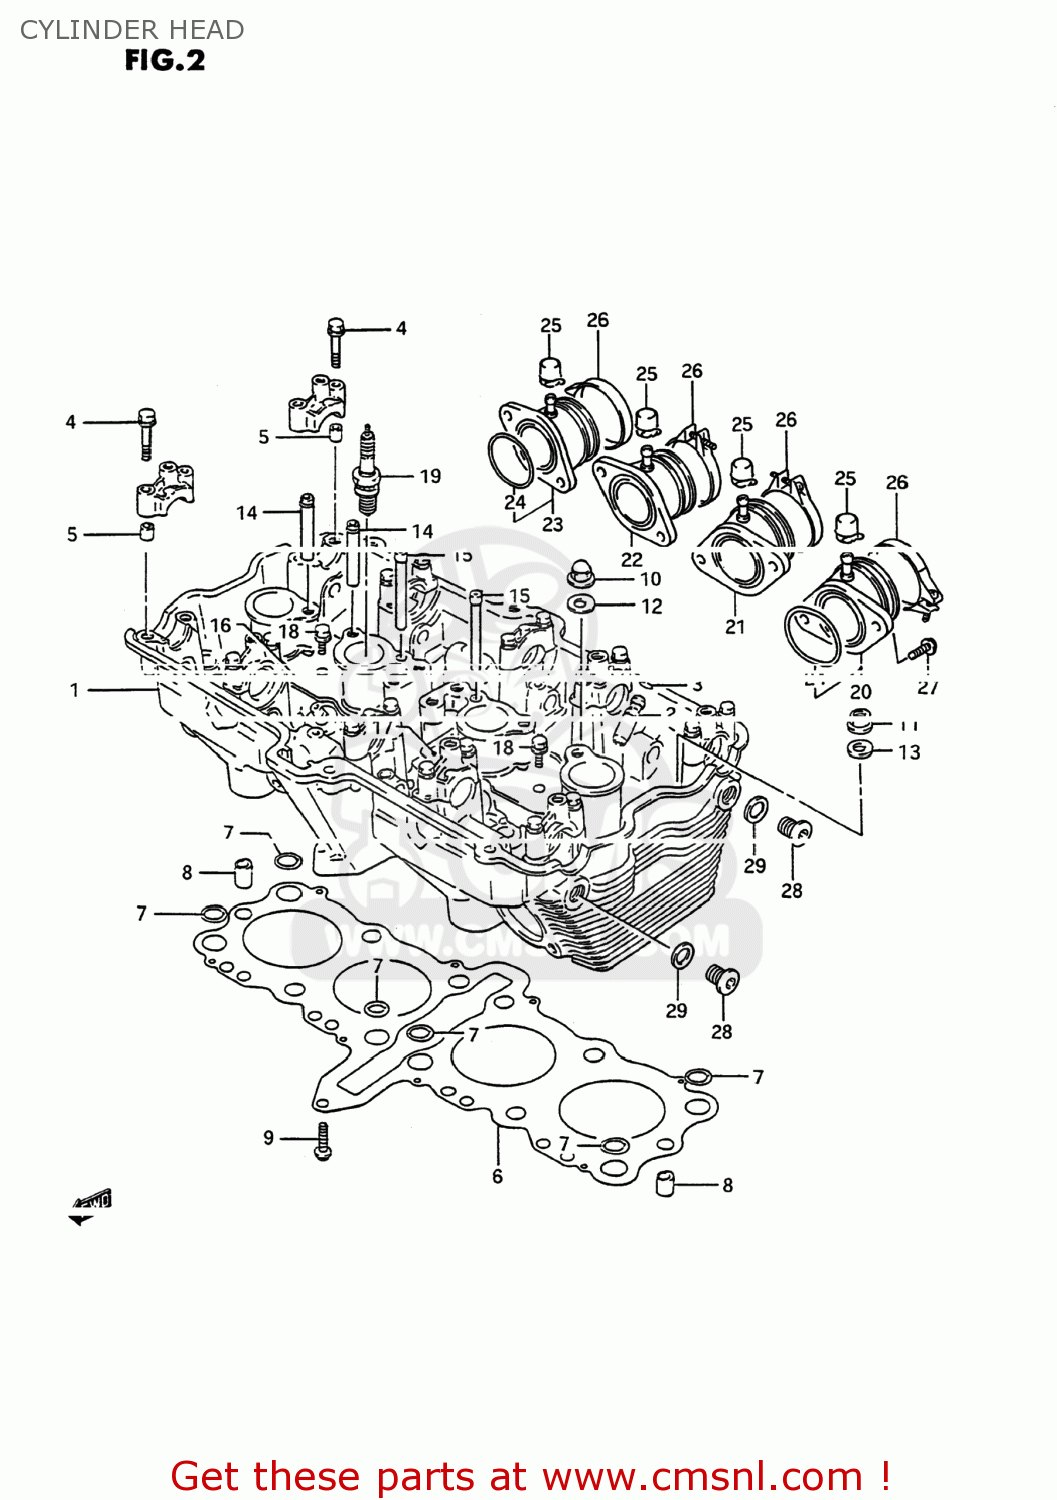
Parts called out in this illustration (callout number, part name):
1	HEAD ASSEMBLY,CYLINDER
2	GUIDE,VALVE
3	RING,SNAP
4	BOLT(6X39)
5	PIN(6.2X8X11)
6	GASKET,CYLINDER HEAD (NAS)
7	O RING(D:2.6,ID:12.1)
8	PIN
9	BOLT
10	NUT
11	NUT
12	GASKET(10.2X20X2).3 (NAS)
13	WASHER (10.5X22X2.3)
14	PIPE,OIL NO.1
15	PIPE,OIL NO.3
16	PLATE,OIL PIPE,R
17	PLATE,OIL PIPE,L
18	BOLT
19	PLUG,SPARK(DR8ES)
20	PIPE,INTAKE NO.1
21	PIPE,INTAKE NO.2
22	PIPE,INTAKE NO.3
23	PIPE,INTAKE NO.4
24	O RING(D:2.4,ID:39.7)
25	CAP
26	CLAMP
27	SCREW
28	PLUG
29	GASKET(13.8X18.8X4.8) (NAS)
